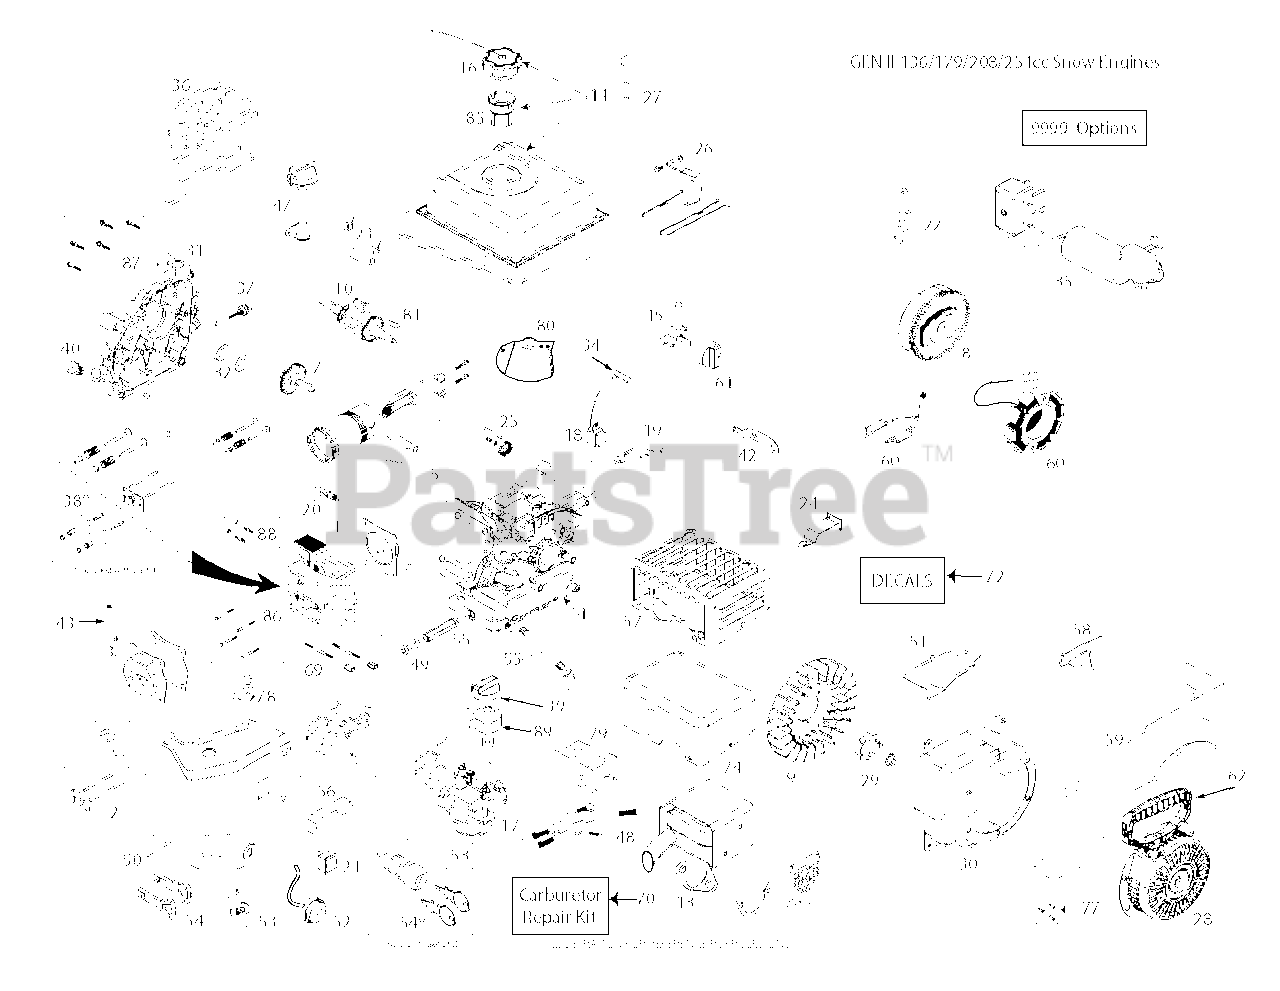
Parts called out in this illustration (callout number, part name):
1	CYLINDER.HEAD.ASM.W/GASKET.254
2	KIT.PUSH.ROD.&.PLATE.W/VC.GASK
3	COVER.VALVE.W/GASKET.254CC
4	CYLINDER LCT 254 FT OIL DRAIN
5	PISTON.&.ROD ASSEM.254CC
7	CAMSHAFT.MCR.W/GASKET.254CC
8	FLYWHEEL.ELEC.STRT.(8.MAGNETS)
9	KIT.COOLNG.FAN.SERV(SK208-4000
10	CRANKSHAFT.KEYED(#18).SNOW.254
13	MUFFLER.ASSEM.GEN2.SNOW.254CC
14	FUEL.TANK.SNOW.2.7L.BLACK.254C
15	FUEL.PETCOCK.SNOW(SKSN4900)
16	FUEL CAP OVERSIZED CLICK STYLE
17	CARBURETTOR LCT 254 W/IDLEDOWN
18	COIL.ING.CDI.HI TEMP.SKSNO416.
20	PLUG.SPARK.PLAT.SKSN2404.1
21	SWITCH.ON/OFF(SKSN-0403)
22	SHIELD.FLYWHEEL.ELEC.STRT.208C
23	FUEL HOSE KIT
24	BRACKET.SPEED.CNTRL.FIXED.254C
25	GOVENOR.GEARS ASM(SK2082900)
26	KIT.GOVERNOR.ARM.&.LINK.254CC
27	KIT.GOVERNOR.CRANK(SK208-3100)
28	RECOIL.STRT.ROUND(BLK) SNOW
29	STRTER.CUP(NON-SLOT)SKSN0601.2
30	BLOWER HSG.LCT 254 GLOSS BLK S
31	CRANKCASE.CVR.PRESS.IN.HI-OIL.
32	KIT.SEAL.OIL.2.PIECES.254CC
34	SPARK.PLUG.BOOT.SNW,SKSN4691.1
35	ELEC.START.GEN2.SKSN0451.1
36	KIT.ENGINE.GASKET.254CC
38	KIT.ROCKER.ARM.W/GASKET.254CC
39	CHOKE.KNOW.SNOW(SKSN4500)
40	NON REMOVABLE PLUG
43	TUBE.BREATHER.LCT.208
47	TUBE ASSY HIGH OIL-FILL
48	WIRE.HARNESS.SNOW
49	KIT.OIL.DRAIN.PLUG(SK2089911
50	KIT.HEATER.BOX.SNOW.254CC
52	PRIMER.BULB.WITH HOSE (SNOW)
53	SWITH.KEY.ASSEM.SNOW.SINGLE.ST
54	KEY SET(2 KEYS) SKSN0407.1
55	OIL PIPE DRAIN LCT 254
56	SHIELD.CARBURETOR.VAPOR
58	SHIELD.GOVERNOR.LINKAGE.254CC
59	FUEL TANK SKIRT SHIELD LCT 254
60	208CC 60W ALTERNATOR
61	FUEL KNOB-SNOW
62	HANDLE.RECOIL.DELUXE.LCT
65	TAPPET.KIT.LCT.208CC
69	CARB.STUDS & COUPLING KIT.SNOW
70	CARB.REPAIR.KIT.LCT.SK9900.2
72	ARIENS 254 SNOW DECAL KIT
74	COVER.MUFFLER.HEAT.SHIELD.
77	BOLT.KIT.RECOIL.LCT.ALL.ENGINE
79	COVER.CARBURETOR.SNOW
80	SHIELD.GOVERNOR.LINK.SNOW.254C
81	KEYS.FLYWHEEL.136/291CC.5PACK
82	SPACER.CARBURETOR.208CC.LCT
85	STRAINER.FUEL.TANK.LCT.208CC
86	KIT.BOLT.CYLINDER.HEAD.(4PC)
87	KIT.BOLT.CRANKCASE.COVER.6PC
88	STUD.MUFFLER.KIT.LCT
89	KNOB LCT.SKSN5325.1 SPEED
9999	JET HIGH ALTITUDE LCT 5000 25
